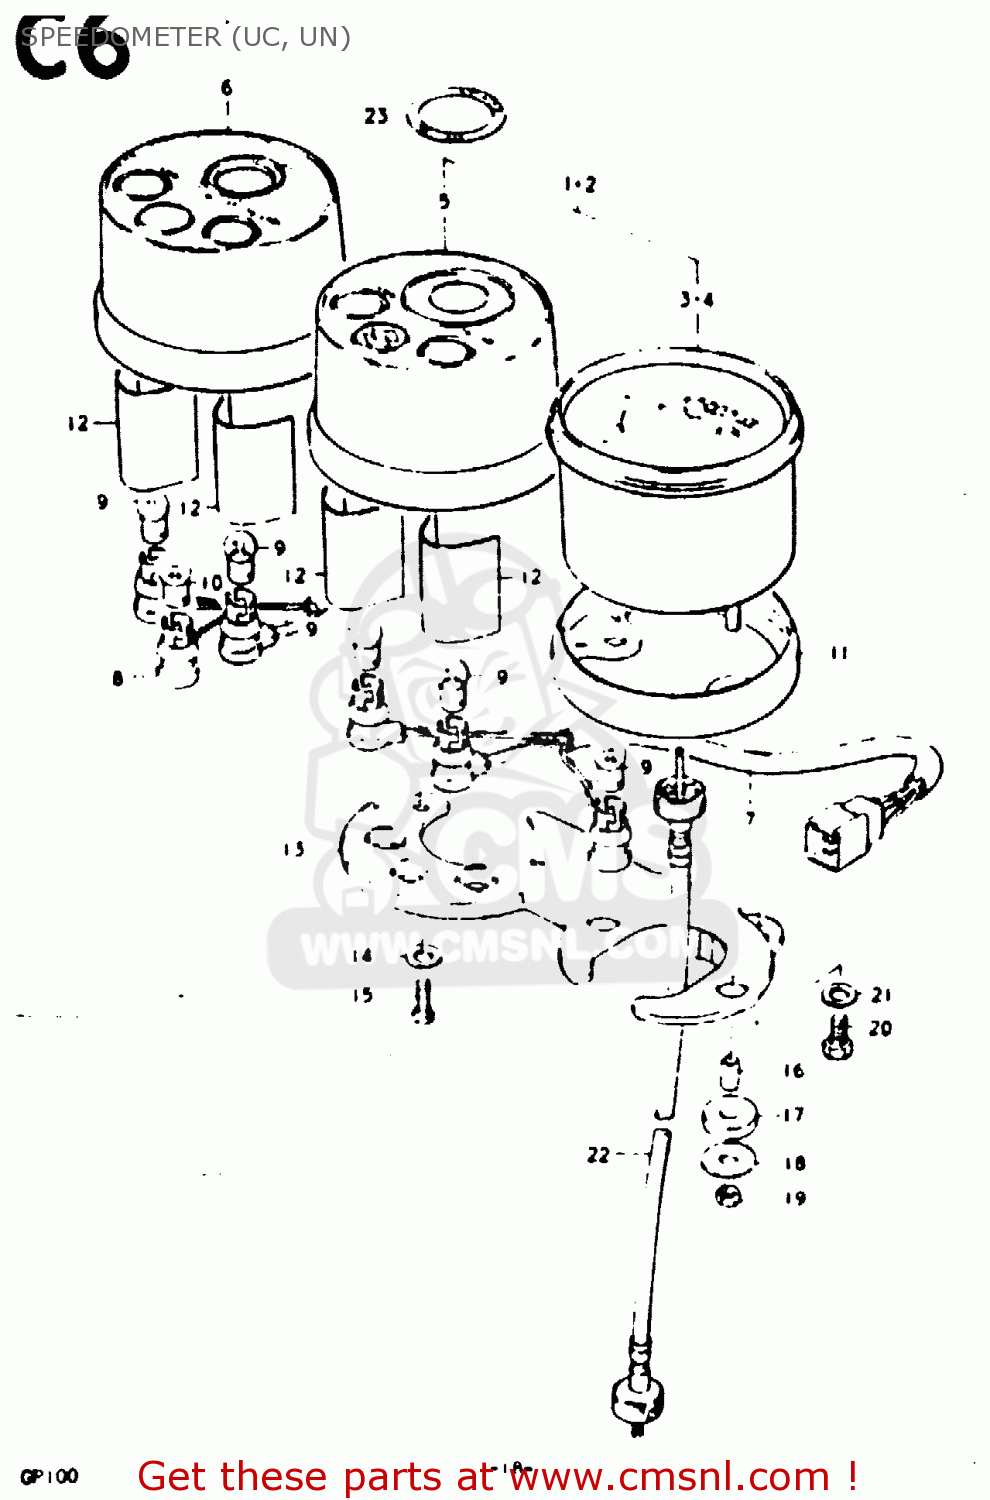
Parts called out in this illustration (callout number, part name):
1	SPEEDOMETER ASSY (KILO SCALE)
2	SPEEDOMETER ASSY (MILE SCALE)
3	SPEEDOMETER
4	SPEEDOMETER ASSY
5	CASE
6	CASE,PILOT BULB
7	SOCKET
8	SOCKET
9	BULB(6V/3W)
10	BULB(6V1.7W,STANLEY,A61A)
11	CUSHION
12	REFLECTOR,PILOT LAMP
13	BRACKET
14	WASHER
15	BOLT
16	SPACER
17	CUSHION,SPEEDOMETER
18	WASHER (5.5X18X1.6)
19	NUT
20	BOLT
21	WASHER
22	CABLE ASSEMBLY,SPEEDOMETER
23	LABEL (IGNITION SWITCH INDICATION)
